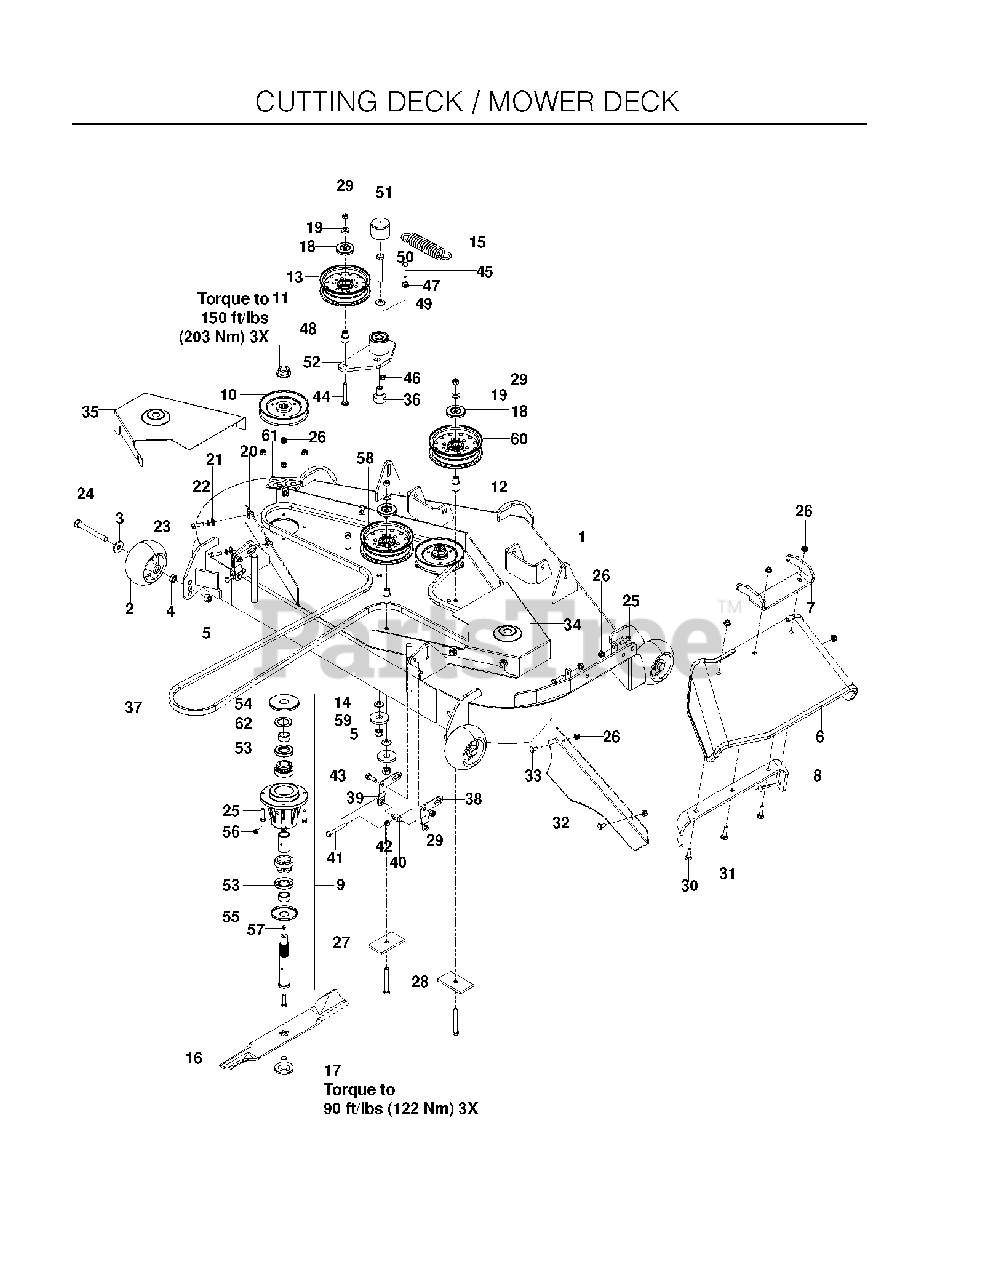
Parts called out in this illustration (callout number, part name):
1	DECK W/DECALS 52 DIX
2	GAUGE WHEEL
3	WASH USS FLAT 1/2
4	NUT 1/2 HEX JAM
5	NUT 1/2-13 HEX NYLOC ZD
6	CHUTE, RUBBER DISCHARGE 52/61"
7	PIVOT BRACKET - CHUTE
8	BRKT, REINF - CHUTE 52/61"
9	HOUSING ASM, 52/61
10	PULLEY 52
11	NUT FLANGE 3/4-16
12	IDLER BUSHING
13	IDLER PULLEY
14	WASHER 1/2" FLAT
16	BLADE, 18"
17	BLADE BOLT/WASHER
18	DUST SHIELD
19	WASHER, 3/8 THICK
20	U-CLIP 5/16-18 NUT RETAINER
21	WASHER 5/16 FLAT
22	WASHER 5/16 LOCK
23	HCS 5/16C X 3/4
24	HCS 1/2-13 X 4 GR 5 ZD
25	HCS 5/16C X 1 1/4
26	5/16-18 NYLOC FLANGE NUT
27	SUPPORT PLATE
28	HCS 3/8C X 3
29	NUT 3/8-16 NYLOC
30	BOLT, CARRIAGE 5/16X1-1/4
31	RHSNB 5/16-18 X 1-1/2 GR 5 ZD
32	CONFINEMENT PLATE, 52"
33	CARRIAGE BOLT 5/16C X 5/8"
34	SHIELD, BELT, 52 RT, BLUE
35	SHIELD.BELT.52 LT.BLUE.DIXON
36	PIVOT, BEARING
37	BELT, DECK 52"
38	PITCH, ADJUST, RT
39	PITCH, ADJUST, LT
40	TRUNION, PITCH
41	HCS 5/16-18 X 2 1/2 TPBLT
42	NUT 5/16C HEX
43	HCS 3/8C X 1
44	RHSNB 3/8-16 X 2.75
45	HCS 3/8-16 X 1-1/2
46	NUT 3/8-16 HEX JAM
47	NUT 3/8C WHIZ
48	BUSHING, IDLER
49	CONTACT BELLSPR 1/2
50	HCS 1/2C X 3 1/4
51	CAP, VINYL
52	ARM-IDLER W/BRG
53	SHAFT SEAL
54	TOP DUST CAP
55	BOTTOM DUST CAP
56	PLUG-VENTED
58	PULLEY - IDLER, 6IN WIDE
59	WASHER, SUPPORT
60	PULLEY IDLER, 6" NARROW
61	DECAL, 52"
62	MACHINE BUSHING
